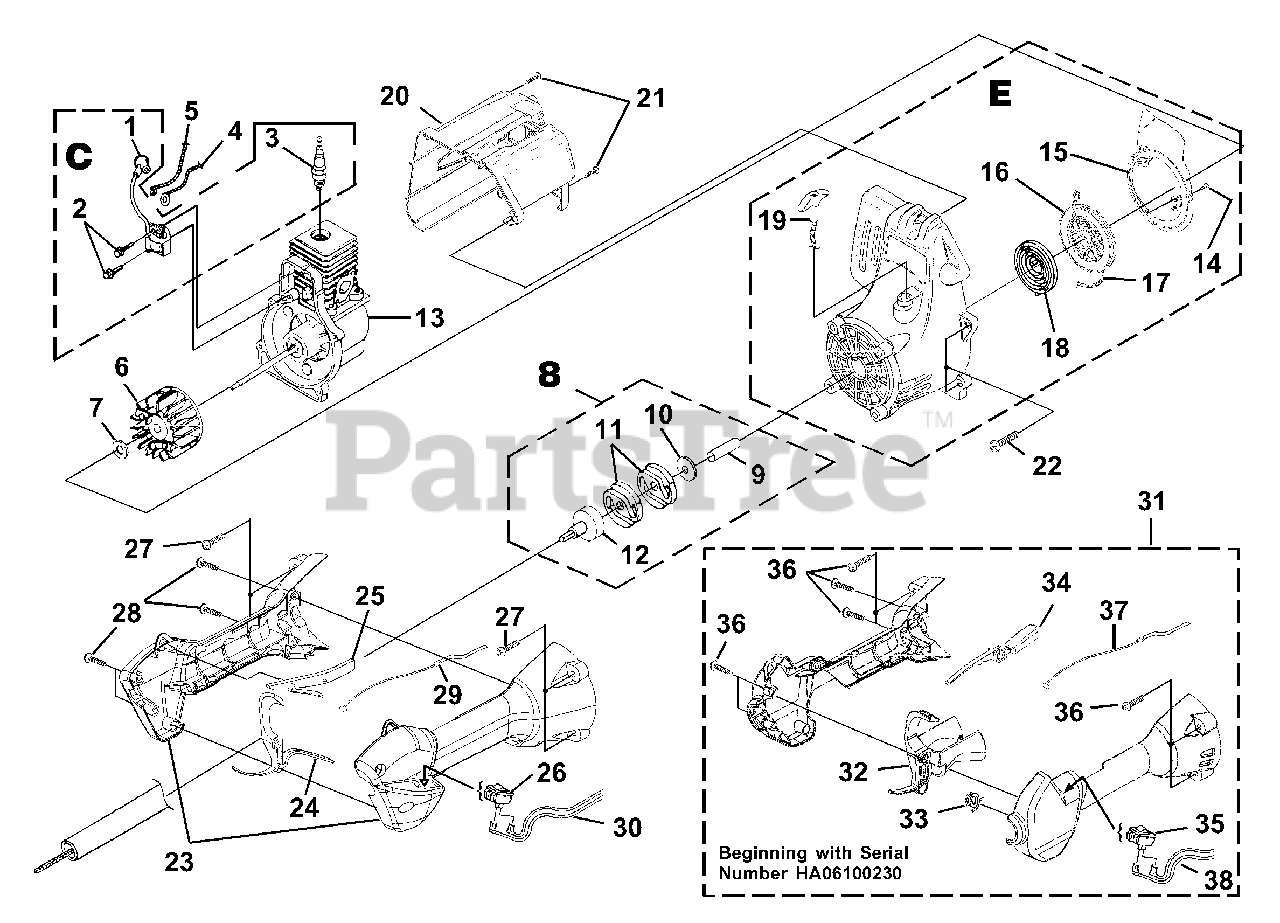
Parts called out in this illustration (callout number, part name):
1	TERMINAL & COVER
2	SCREW-Taptite (8-32 X 1")
3	SPARK PLUG
4	LEAD-Electrical
5	LEAD-Electrical
6	ROTOR KIT
7	WASHER-Flat
8	CLUTCH AND DRUM KIT
9	SPACER
10	WASHER-Flat
11	CLUTCH
12	CONNECTOR AND DRUM
13	SHORT BLOCK
14	SCREW-Thread Form (8-16 X 1/2")
15	BAFFLE-Air
16	PULLEY-Starter
17	ROPE-Starter (42")
18	SPRING & CONTAINER
19	GRIP-Starter (Yellow)
20	HOUSING-Rear Kit
21	SCREW-Plastite (10-14 X 3/4")
22	SCREW-Taptite (10-24 X 3/4")
23	CONTROL HANDLE ASSY.
24	TRIGGER-Throttle
25	THROTTLE INTERLOCK
26	SWITCH
27	SCREW-Taptite (10-14 X 7/8")
28	SCREW-Taptite (10-24 X 3/4")
29	CABLE-Throttle
30	LEAD-Electrical
31	CONTROL HANDLE ASSY.
32	TRIGGER-Throttle
33	SPRING
34	THROTTLE INTERLOCK
35	SWITCH
36	SCREW-Taptite (10-14 X 1")
37	CABLE-Throttle
38	LEAD-Electrical
C	IGNITION KIT
E	COMPLETE STARTER ASSEMBLY
